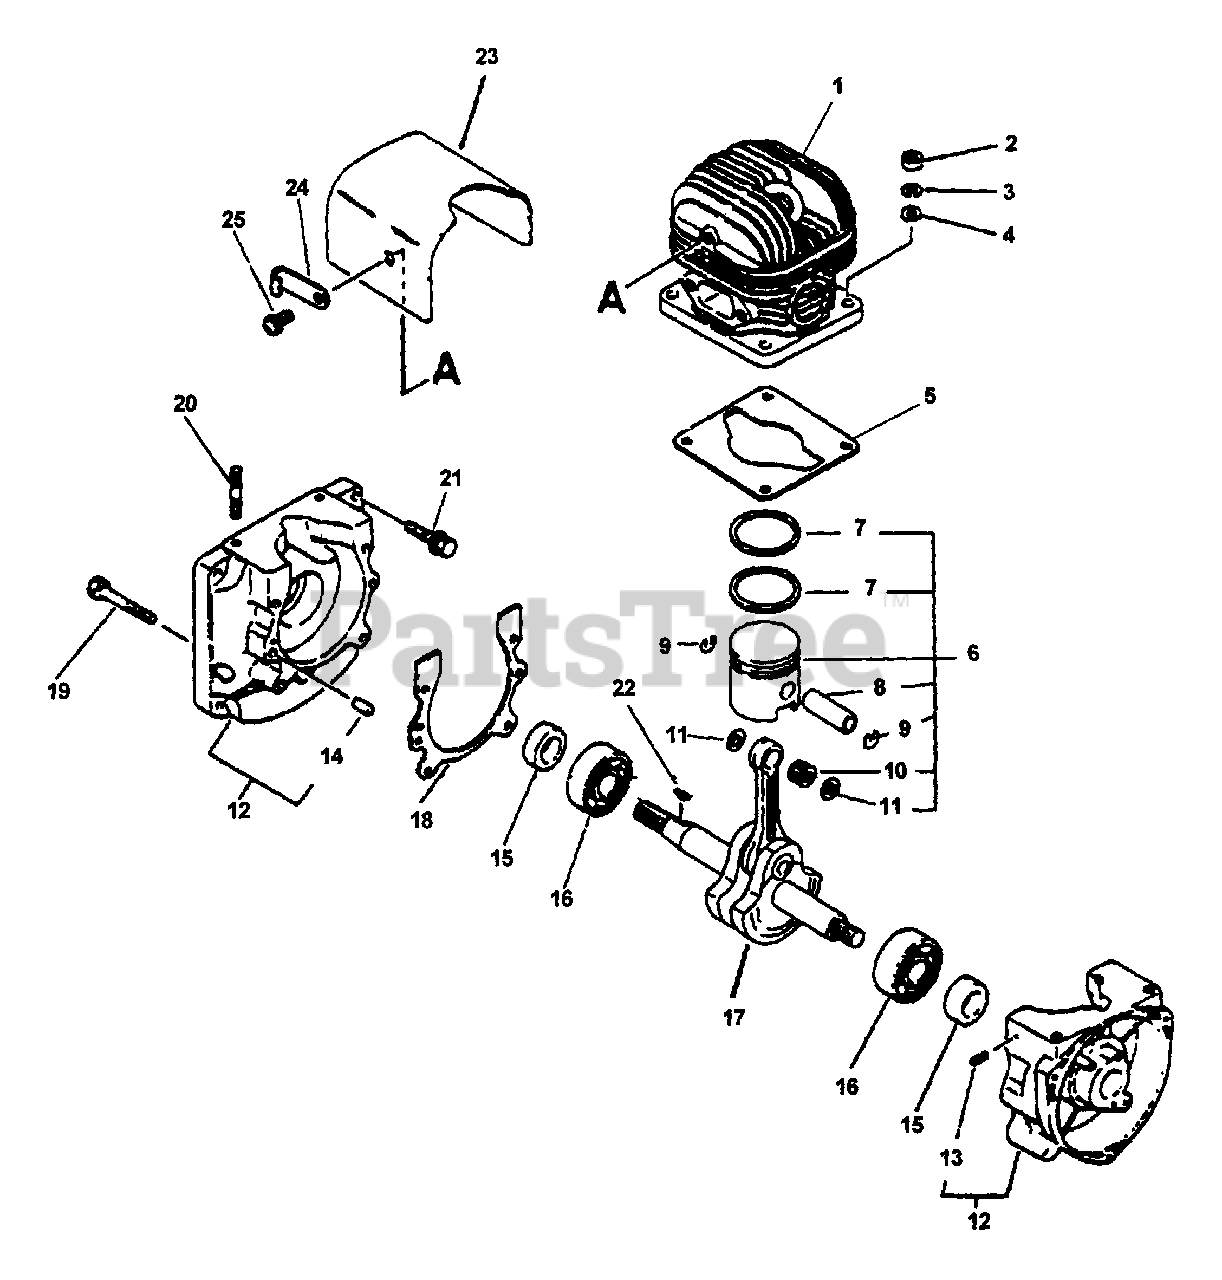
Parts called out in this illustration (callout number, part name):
1	CYLINDER
2	LOCKNUT - 6
3	LOCKWASHER - 6
4	WASHER - 6
5	GASKET, CYLINDER
6	PISTON KIT
7	RING, PISTON
8	PIN, PISTON
9	RING, RETAINING - 8
10	BEARING, NEEDLE
11	SPACER, PISTON
12	CRANKCASE KIT
13	CONNECTOR
14	PIN - LOCATING
15	SEAL, OIL
16	BEARING, BALL - 6202
17	CRANKSHAFT ASSY
18	GASKET, CRANKCASE
21	BOLT - 5X25
23	SHIELD, CYLINDER
25	BOLT - 6X10
